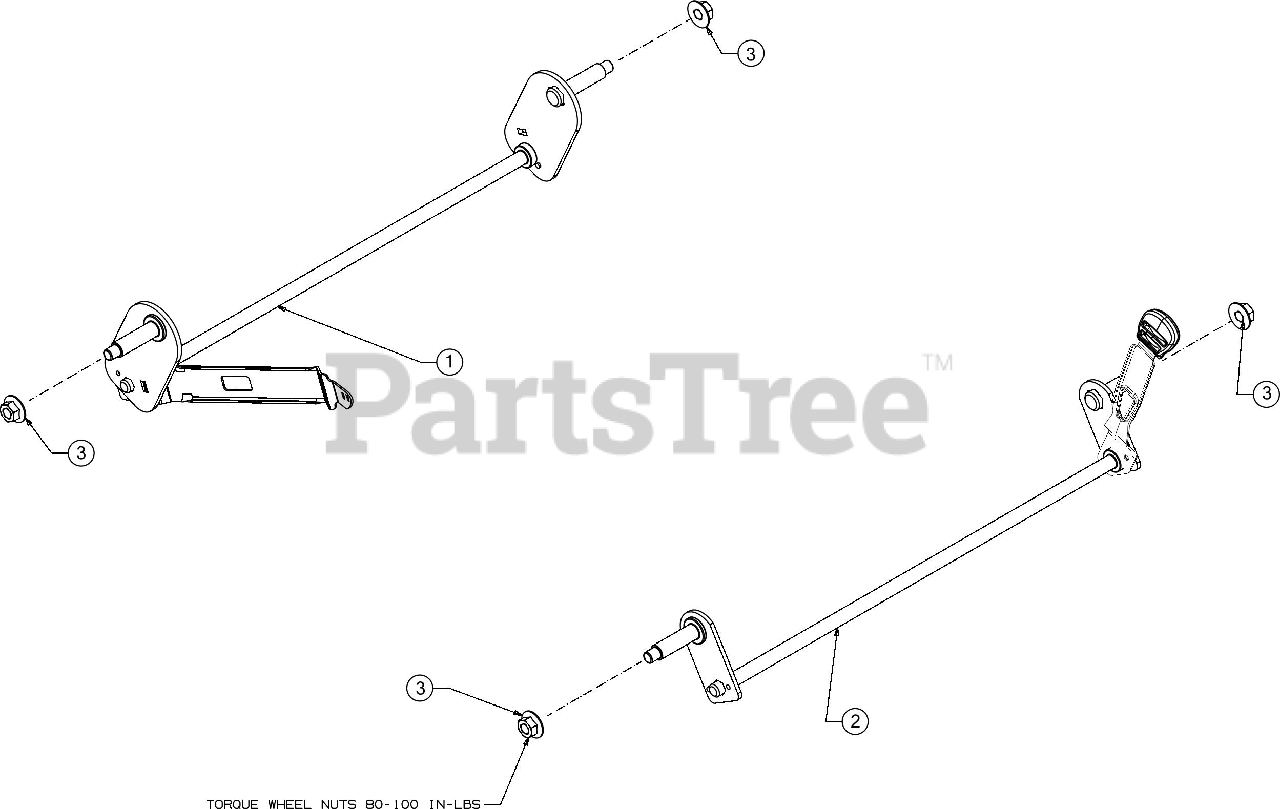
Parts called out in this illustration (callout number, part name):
1	11" REAR AXLE ASSEMBLY
2	FRONT AXLE ASSEMBLY
3	FLANGE LOCK NUT
